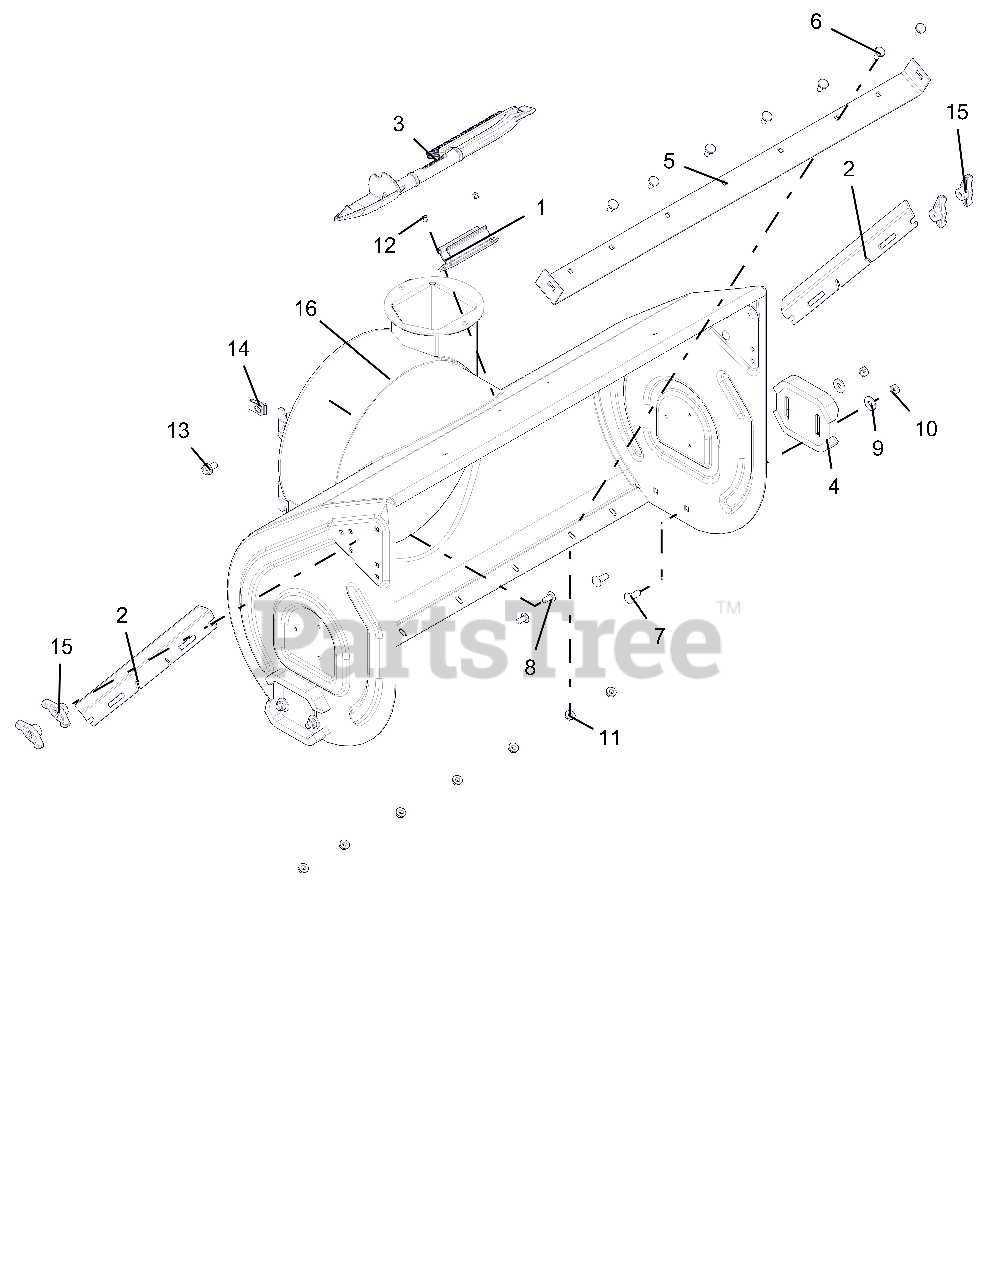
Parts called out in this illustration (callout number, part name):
1	MOUNT, SNOW CLEAN OUT
2	CUTTER, DRIFT
3	DEVICE, SNOW CLEAN OUT W/BRUSH
4	RUNNER, SKID SHOE
5	BLADE, SCRAPER-36"
6	BOLT, MODIFIED HEAD CARRIAGE
7	@BLT-RDHDSHSQNK.38-16X1.0 G5YZ
8	@BLT-RHDSSQNK .31-18X.75 G5YZ
9	@WSHR-FL-STL.438X1.00X.083 YWZ
10	@NUT-LK-CTR .38-16 YWZC
11	@NUT-LK-TOP-FLG .31-18 YWZC
12	RVT-POP .187 YZ
13	BLT-SERHFWH .38-16X.75 YWZC
14	NUT-RTNR .375-16X.37
15	KNOB,WING .31-18 UNC NYL/TALC
16	BLOWER HOUSING W/DECAL 36"
